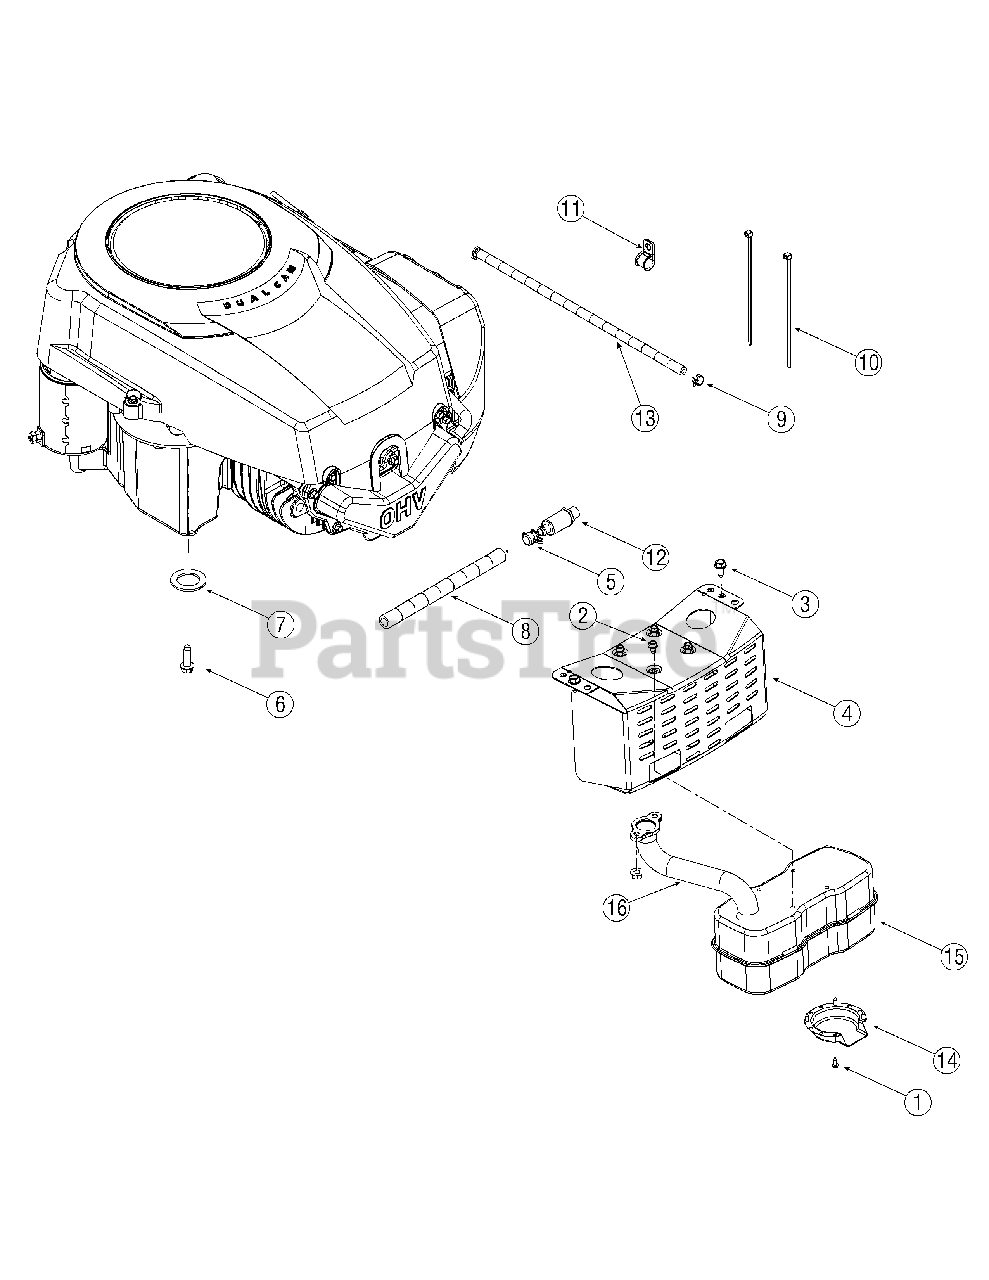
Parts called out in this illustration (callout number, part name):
1	AB Screw #8-18 x 0.5
2	TT Screw 1/4-20 x 0.5
3	AB Screw 5/16-12 x 0.5
5	Oil Drain Cap
6	TT Screw 3/8-16 x 1.00
7	Flat Washer, 1.031 x 1.620 x .095
8	Oil Drain Extension Hose
12	Oil Drain Valve
13	Fuel Line Hose
14	Muffler Deflector
15	Muffler
